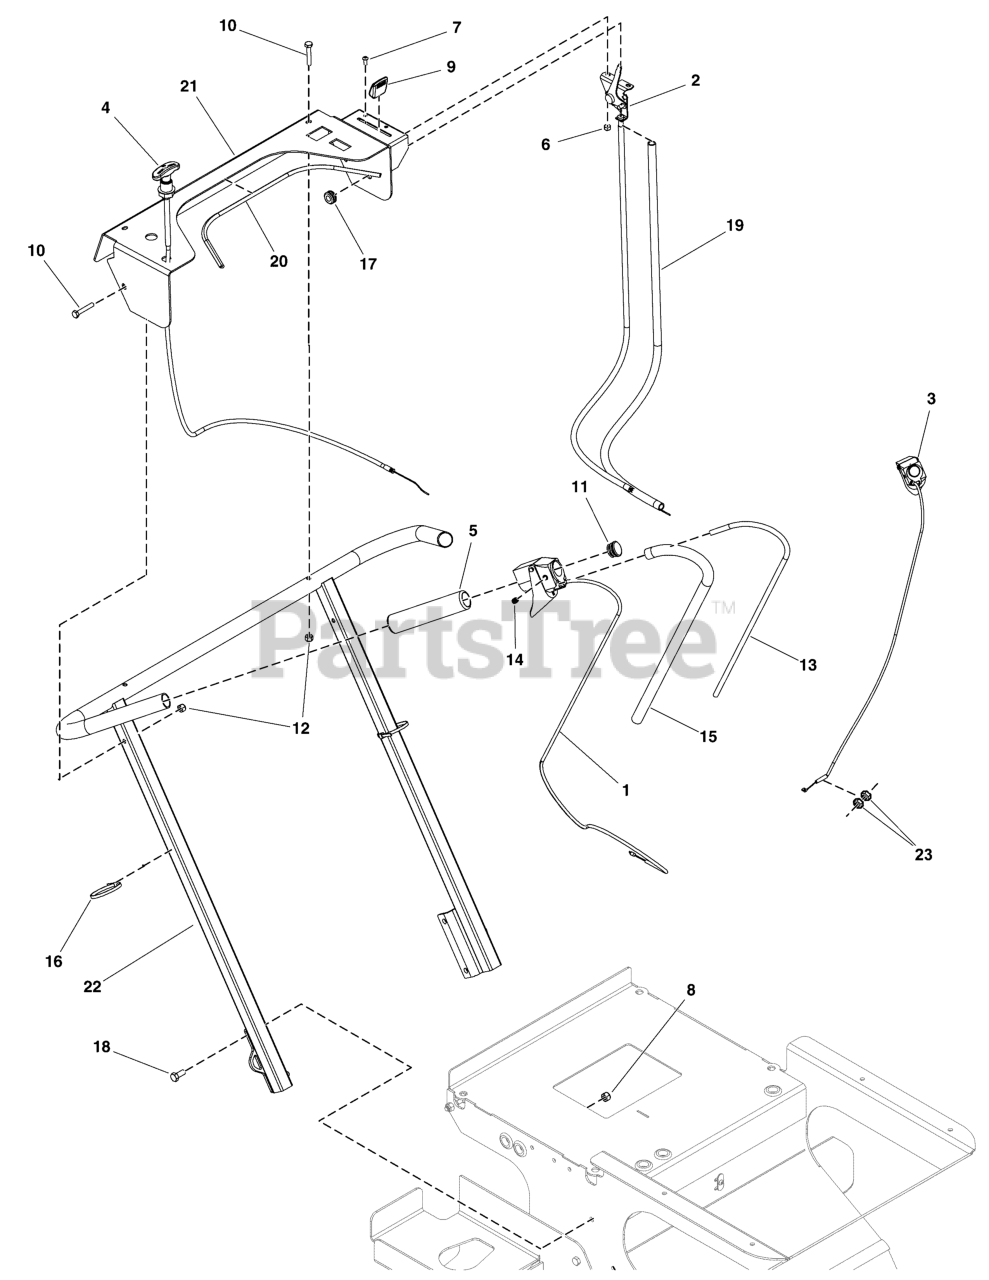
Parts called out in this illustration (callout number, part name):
1	KIT, ROVER/PATHFINDER THROTTLE CABLE
2	CABLE, LEVER ACTION 34"
3	CABLE, SPRAY
4	CABLE, TURN TO LOCK, 35"
5	GRIP, .94 ID X .155 THK X 5.75 LONG
6	NUT-HEX-NYLK, #10-24 SS188
7	SCR-CAP, BSH #10-24 X .500" SS188
8	NUT-HEX-NYLK, 0.3125"-18 SS188
9	KNOB, GATE LEVER
10	SCR-CAP, HEX .250"-20 X 1.500" SSF593C
11	PLUG, 1" TUBE, ROUND
12	NUT-HEX-NYLK, .250"-20 SS188
13	ROD,CABLE SUPPORT
14	SCR-SH, SET .3125"-18 X .375" KCPT SS188
15	THROTTLE CABLE SPLIT LOOM, .500" ID
16	CABLE TIE, .188" W X 7.50" LNG
17	GROMMET, 0.375" I.D., FIT 0.500" HOLE
18	SCR-CAP, HEX .3125"-18 X .750" SS188
19	SPLIT LOOM, GATE CABLE, 28"
20	TRIM, CONSOLE, 18.75 LONG
21	WELD, OPERATOR, HANDLEBAR FRAME - XC
22	WELD, FRAME, HANDLE BAR - XC
23	NUT-HEX, JAM .250"-28 SS188
